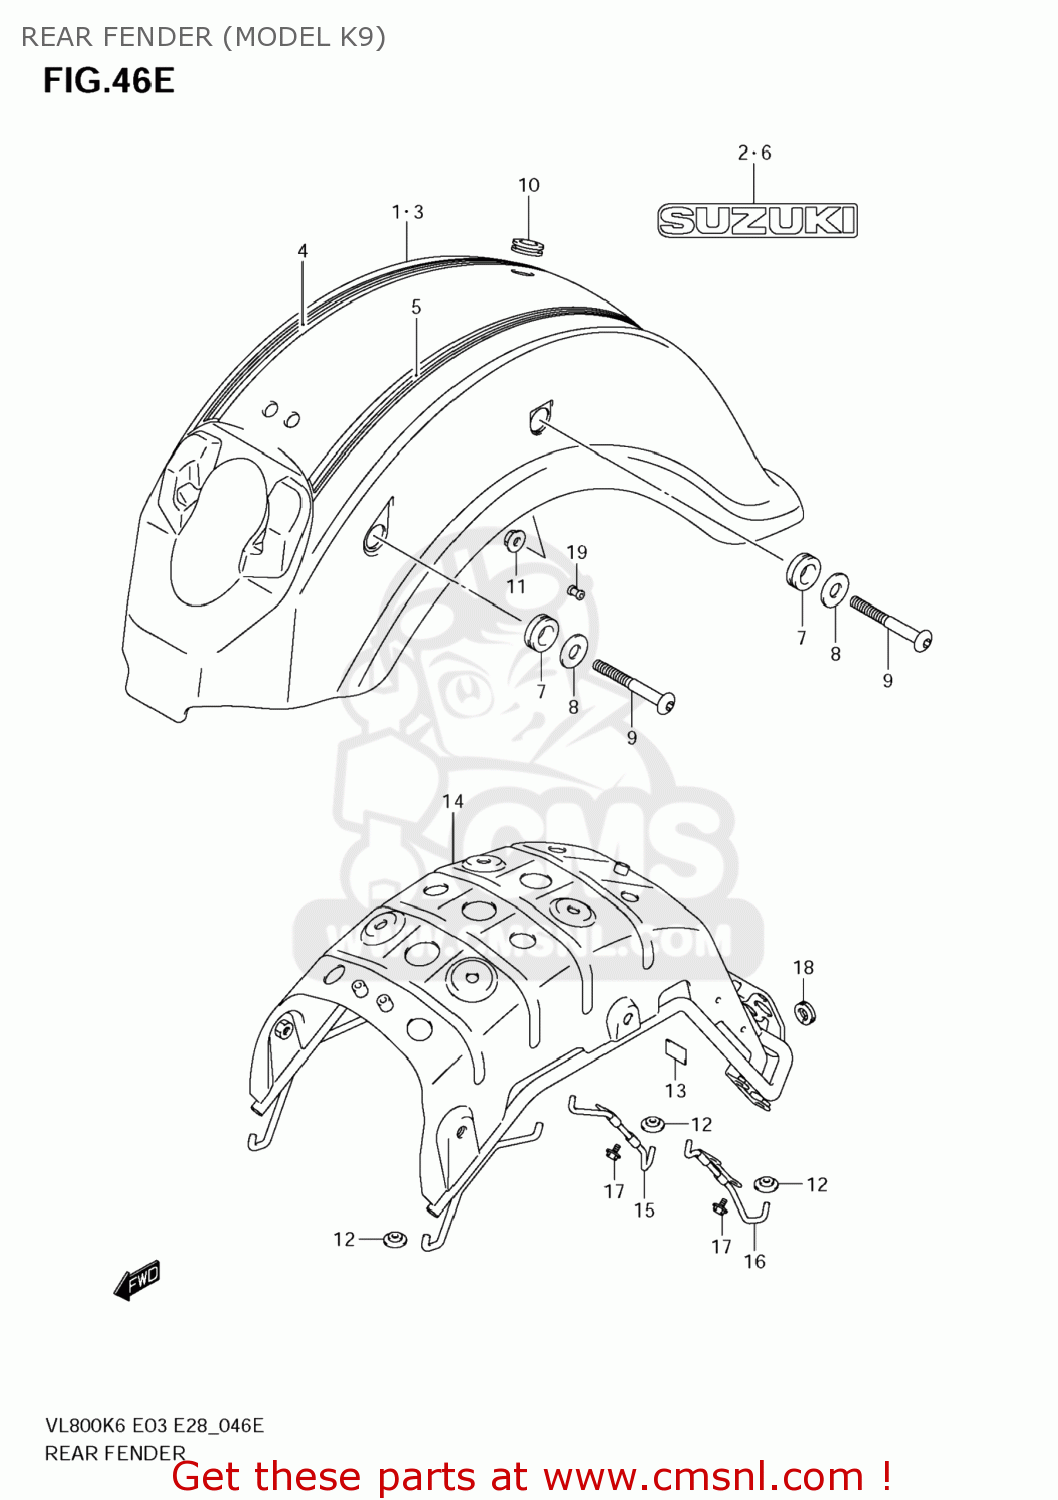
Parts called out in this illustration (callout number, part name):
1	FENDER,RR
2	EMBLEM,SUZUKI
3	FENDER,RR
4	TAPE SET,RR FENDER,R
5	TAPE SET,RR FENDER,L
6	EMBLEM,SUZUKI
7	CUSHION,FRAME COVER UPR RR
8	WASHER(15.5X26X2.3)
9	BOLT,RR FENDER
10	CUSHION
11	NUT
12	CUSHION
13	CUSHION,FRONT FENDER
14	REINF,RR FENDER
15	BRACKET,RR FENDER LWR,R
16	BRACKET,RR FENDER LWR,L
17	BOLT
18	GROMMET
19	PLUG(OD:9)
